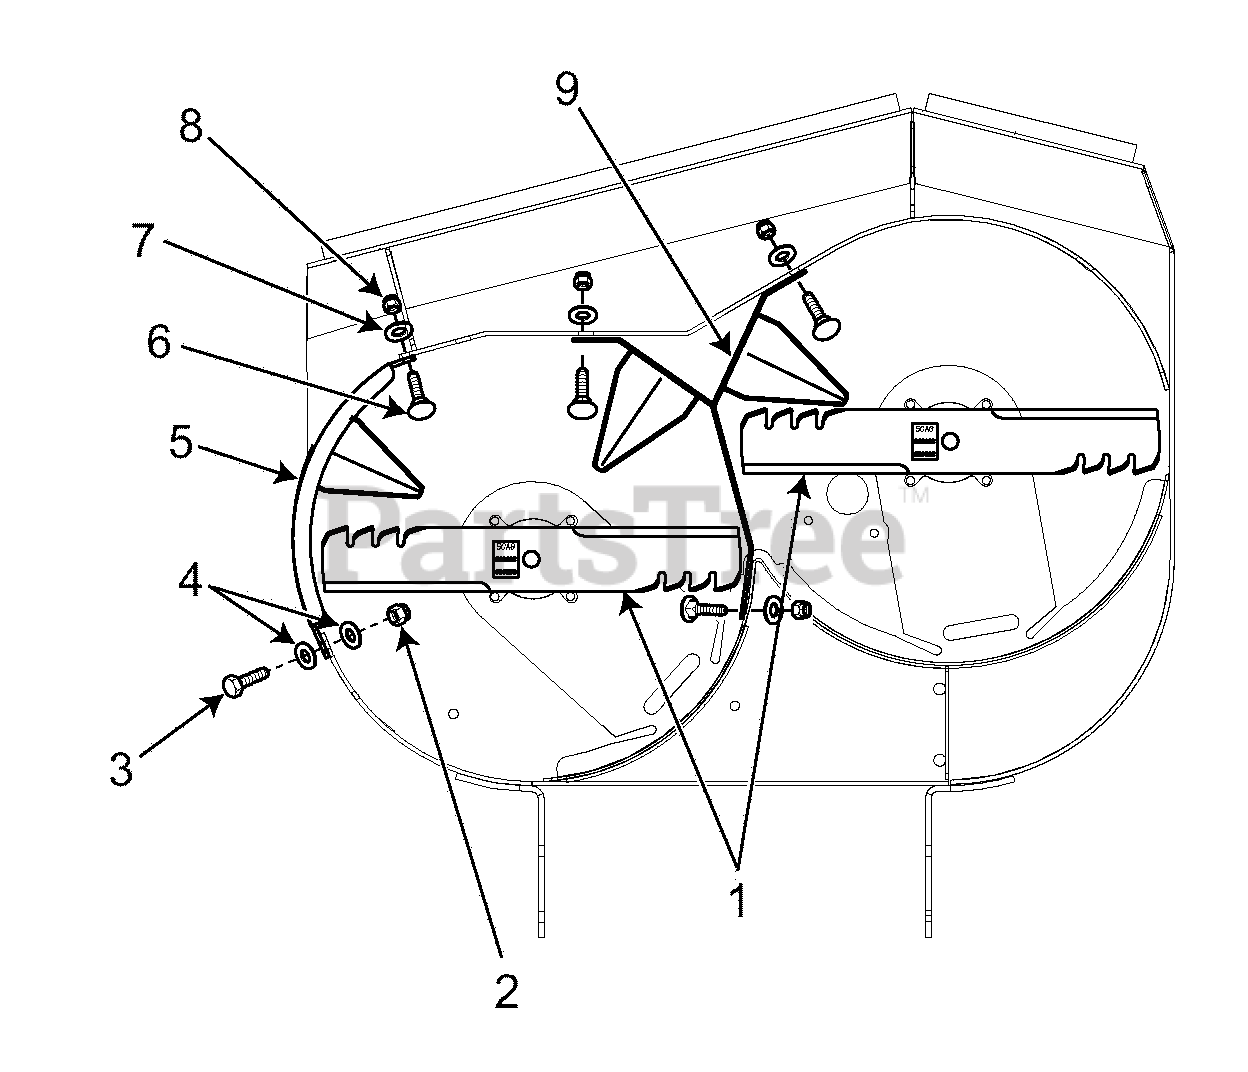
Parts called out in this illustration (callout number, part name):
1	Mulch Blades
2	Elastic Stop Nut 5/16-18
3	H.H. Bolt 5/16-18 x 1"
4	Flatwasher 5/16"
5	Mulch Plate
6	Carriage Bolt 3/8-16 x 1'
7	Flatwasher 3/8"
8	Elastic Stop Nut 3/8-16
9	Mulch Baffle
